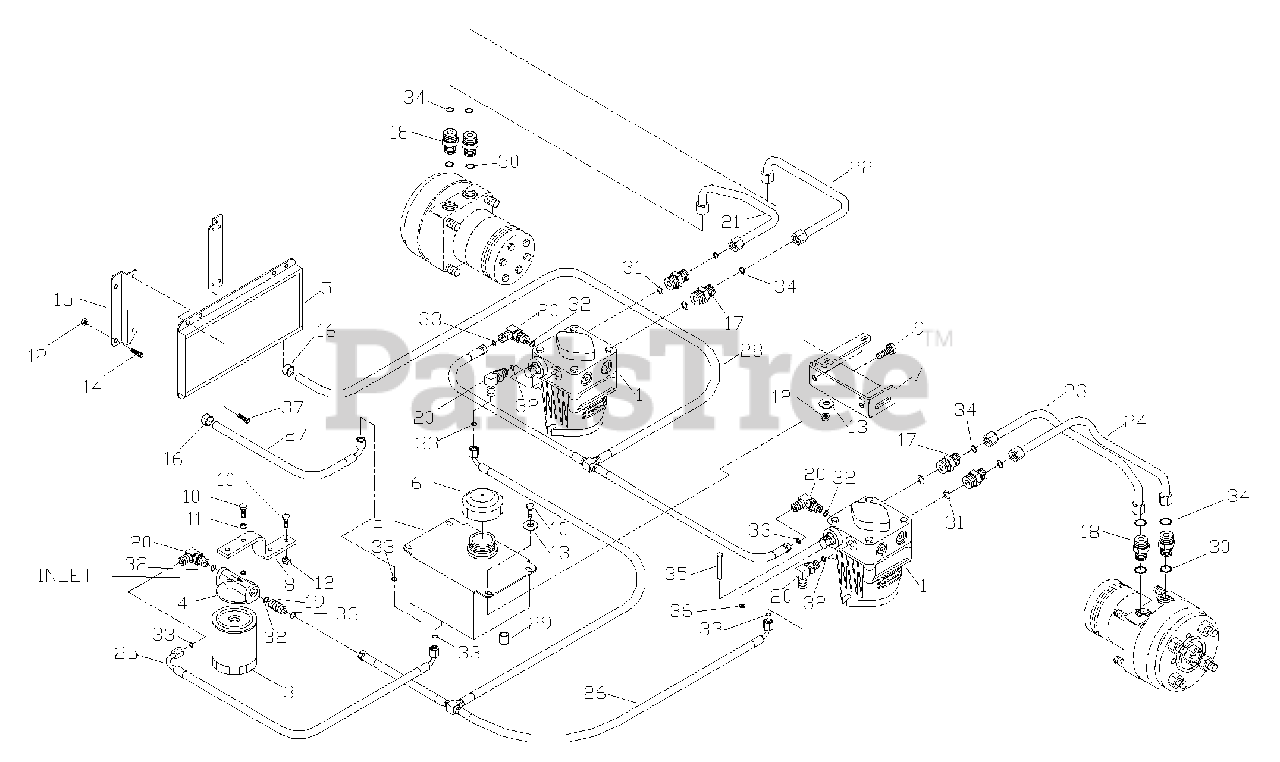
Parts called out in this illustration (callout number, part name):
1	PUMP
4	FILTER HEAD
7	TANK MOUNT LT.
7	TANK MOUNT RT.
8	FILTER BRACKET
9	HCS 5/16 X 3/4
10	HCS 1/4C X 3/4
11	1/4 LOCK WASHER
12	1/4 LOCK NUT
13	1/4 FLAT WASHER
14	HCS 1/4C X 2.0
15	COOLER BRACKET
16	HOSE CLAMP
18	STR. FITTING
26	"T" ASM (SUCTION)
28	"T" ASM (RETURN)
30	7/8 "O" RING
31	3/4 "O" RING
32	3/8 "O" RING
33	3/8 "O" RING FLARE
34	3/8 "O" RING FLARE
37	HCS 1/4 SELF TAP
